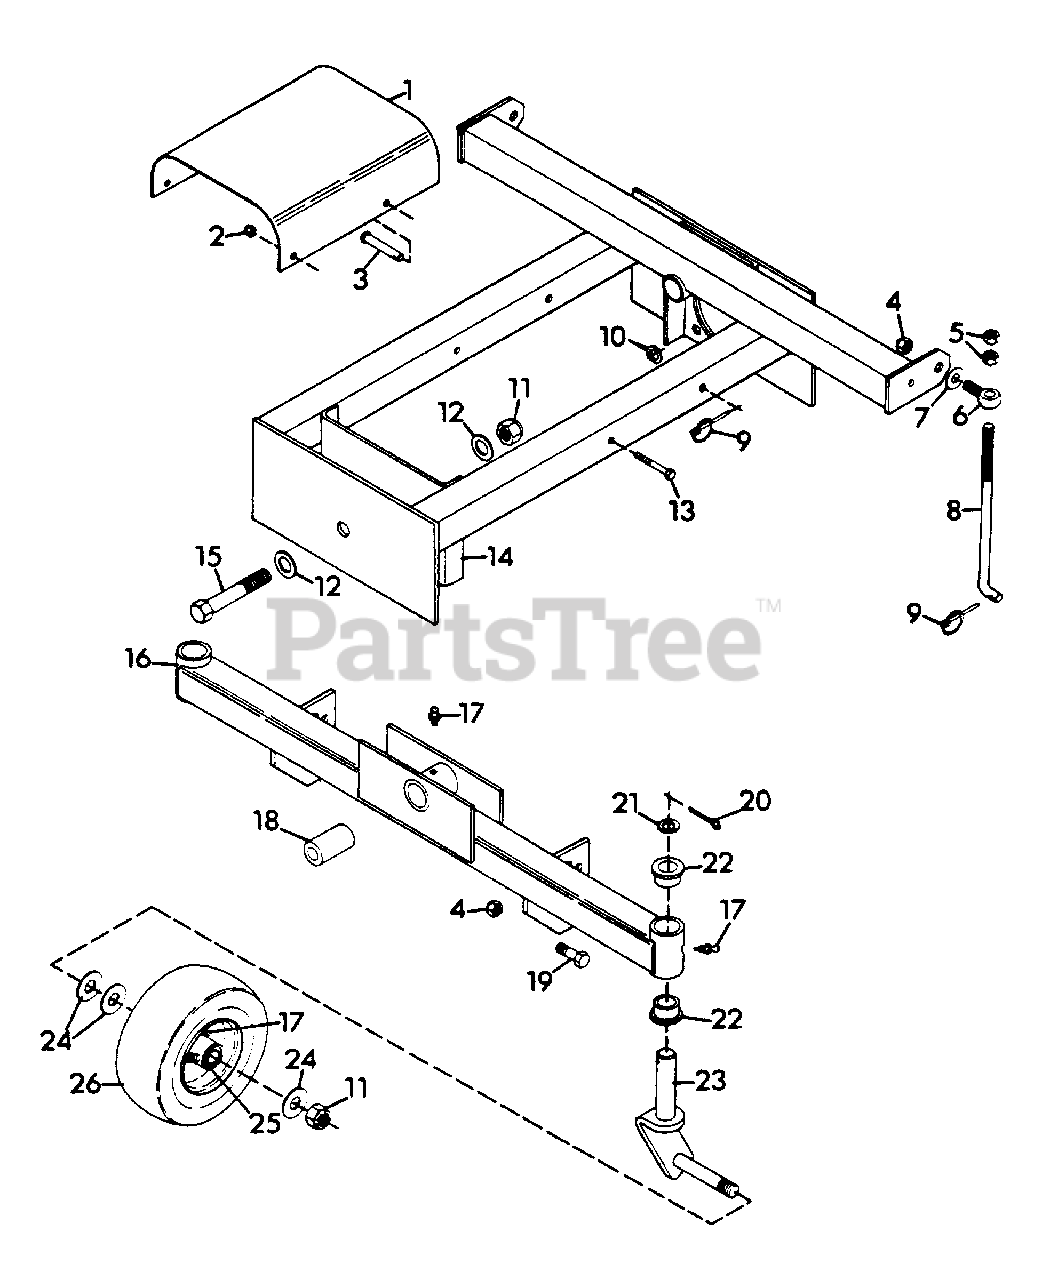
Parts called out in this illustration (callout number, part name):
1	Guard, PTO Shaft
2	Nut, Lock 5/16-18
3	Pin, Clevis
4	Nut, Lock 1/2-13
5	Nut, Jam 1/2-13 Hex
6	Bolt, Eye
7	Washer, Flat .500x1.250x.083
8	Rod, Height Adjustment
9	Pin, Klik
10	Washer, Lock 1/2 Reg.
11	Nut, Lock 3/4-10
12	Washer, Flat .812x1.469x.130
13	Bolt, Hex 5/16-18x2.50
14	Weldment, Mower Frame
15	Bolt, Hex 3/4-10x4.50
16	Weldment,Axle
17	Fitting, Lube 1/4-28
18	Tube, Pivot
19	Bolt, Hex 1/2-13x1.375
20	Pin, Cotter .187x1.625
21	Race, Bearing Thrust
22	Bushing, Pivot
23	Weldment, Caster Fork
24	Washer, Flat .812x1.496x.134
25	Bearing, Gauge Wheel
26	Wheel, Gauge
